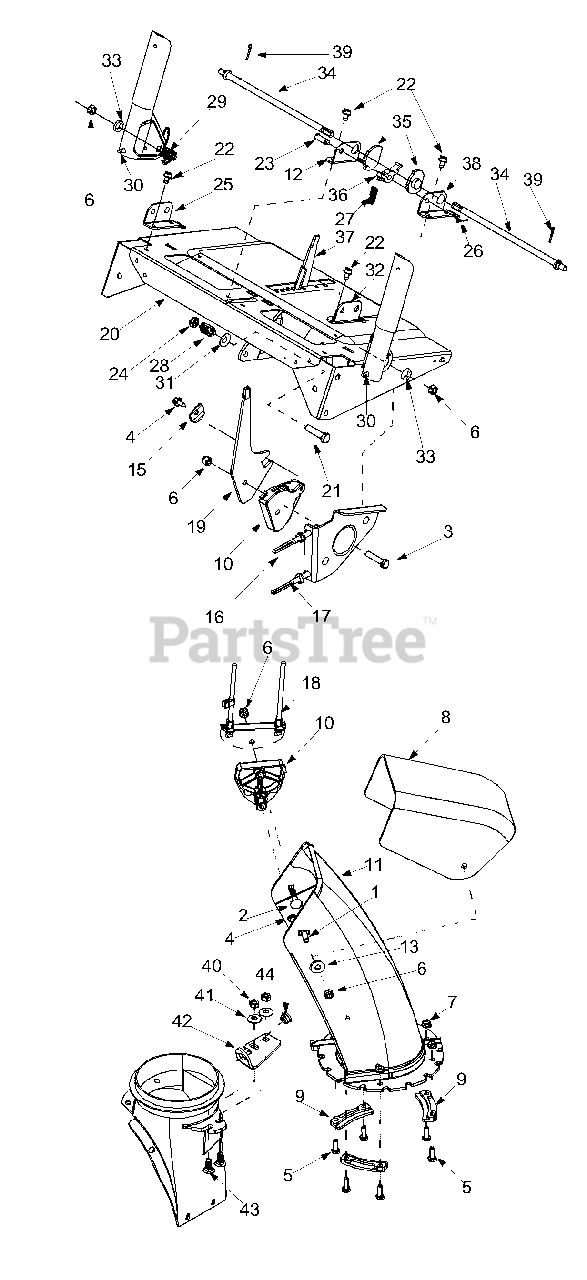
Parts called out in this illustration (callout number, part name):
1	Carriage Bolt 5/16-18 x 1.0"
2	Carriage Bolt 5/16-18 x 1.5"
3	Hex Bolt 5/16-18 x 1.5"
4	Hex AB Screw 1/4-14 x .625"
5	Hex Screw 1/4-20 x .75"
6	Hex Lock Nut
7	Hex Flange Lock Nut
8	Upper Chute
9	Chute Flange Keeper
10	Cable Guide: Chute Tilt
11	Lower Chute
13	5/16 Washer
15	Special Washer
16	Chute Control Cable
17	Chute Cable w/Clip
21	Hex Bolt 3/8-24 x 1.5"
22	TT Screw 1/4-20 x 0.5"
23	Clevis Pin
26	Cotter Pin
29	Torsion Spring
30	Rubber Bumper
31	Bell Washer
33	Special Washer
35	Cam: Handle Lock
36	Pawl: Handle Lock
39	Hairpin Clip
40	Hex Nut 5/16-18
41	Bell Washer
43	Carriage Bolt 5/16-18 x .750"
44	Plastic Bushing
